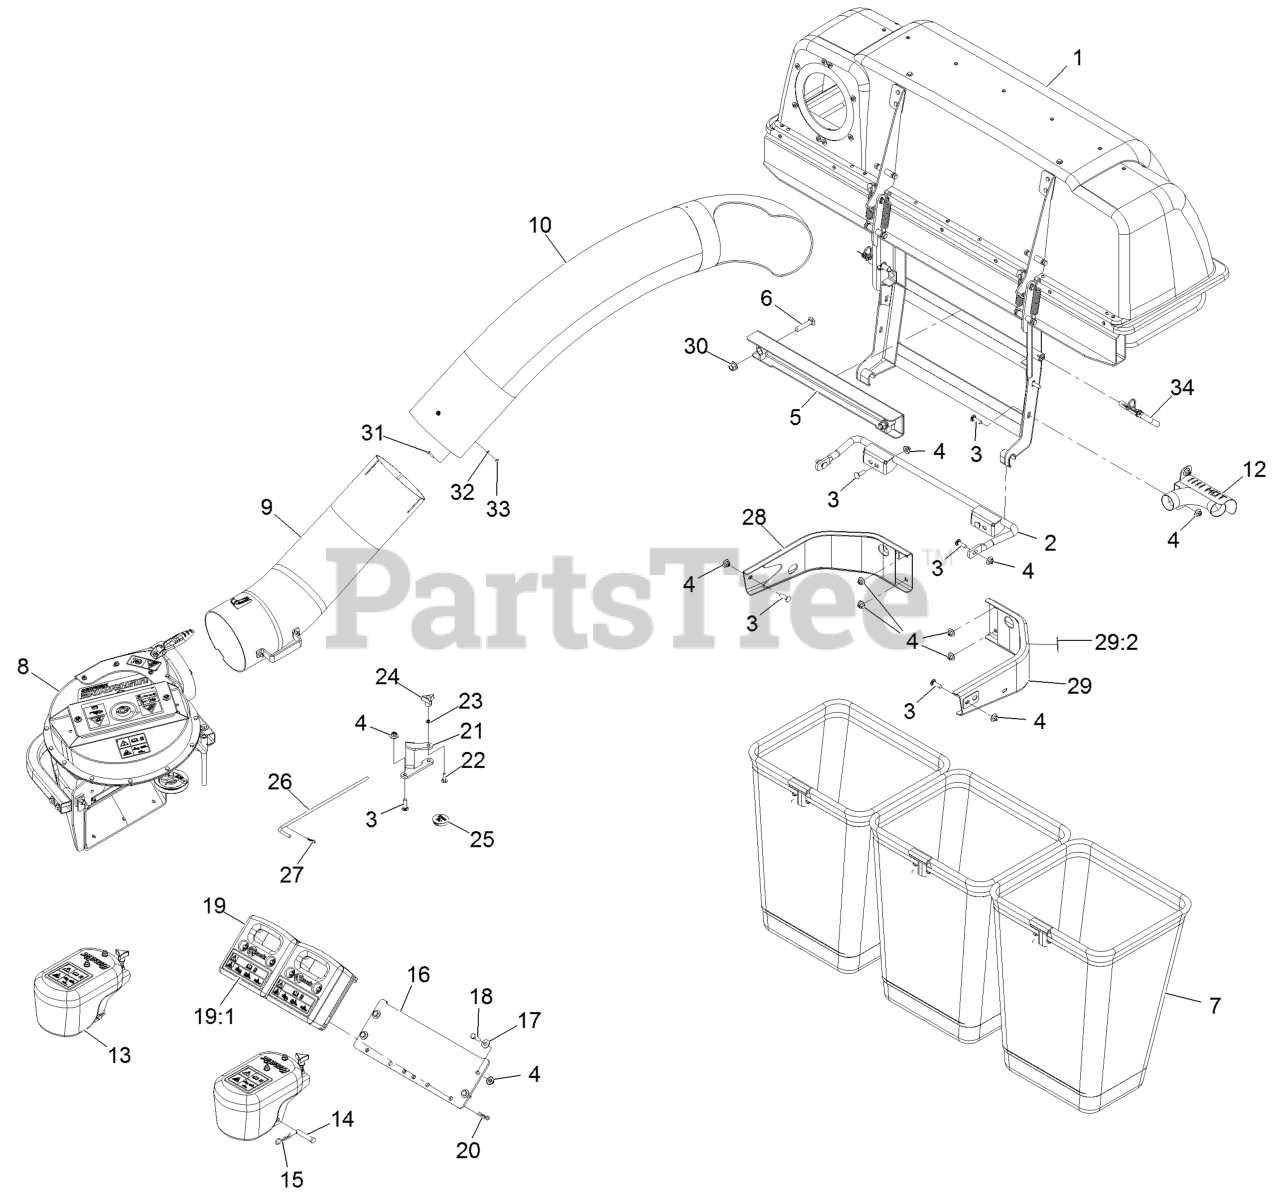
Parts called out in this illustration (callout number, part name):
2	Mount-Bagger, Lower
3	Bolt-Carriage 3/8-16 X 1 1/4
4	Nut-Nyloc 3/8-16 Flg
5	Mount-Bagger, Upper
6	Bolt-Carriage 1/2-13 X 2 1/2
7	Bag And Frame ASM
8	ASM, Blower Large - Svc Only
9	Lower Tube ASM
10	Tube-Upper
12	Exhaust Diverter ASM
13	ASM,Caster Weight
14	Pin-Clevis
15	Hairpin-Cotter
16	Plate, Weight Mounting
17	Washer-3/8 Std
18	Screw-HH 3/8-16 X 1 1/4
19	Asm, Weight (103-6364-01) W/Decals
19:1	Decal-Warning Weight
20	Hairpin-Cotter
21	Bracket,Belt Cover
22	Bolt-Carriage 5/16-18 X 1
23	Ring-Bolt Retaining
24	Knob-3 Prong
26	Pin, Chute Pivot
27	Hairpin-Cotter
28	Bumper-RH
29	LH Bumper ASM
29:2	Decal-Warning
30	Nut-Lock 1/2-13
31	Screw-HWH #10-24 X 3/4
32	Washer-#10 Std
33	Nut-Nyloc #10-24
34	Pin-Mount, Bagger
